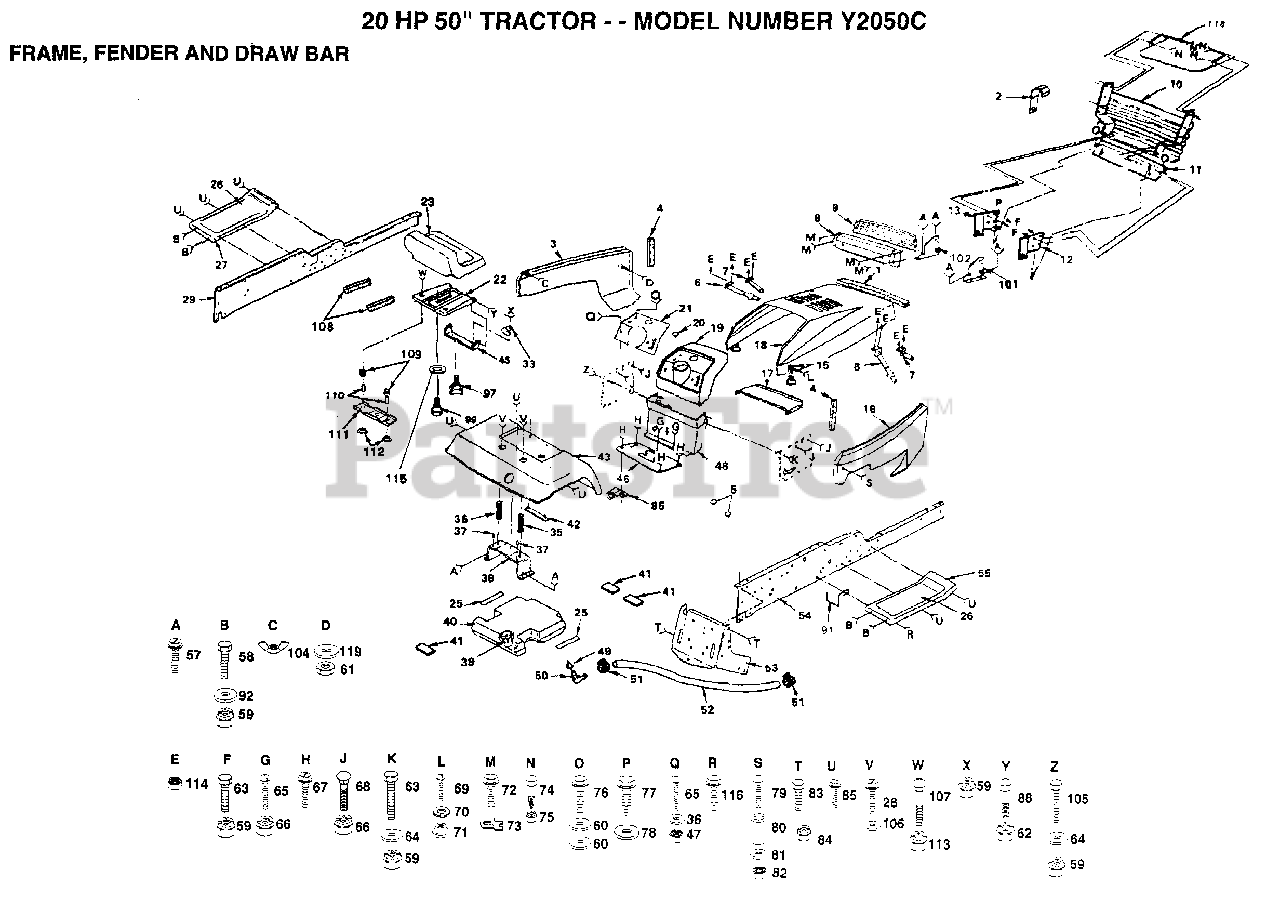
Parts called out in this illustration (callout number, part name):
1	FOAM STRIP T
4	FOAM STRIP T
5	CAP SPRING
9	LENS LT
12	SUPPORT RH YTH
13	SUPPORT LH YTH
15	HOOD LATCH T
16	"PANEL,SIDE RH "
20	PLUG-DASH T
25	PAD IDLER TI
26	FOOTREST PAD
28	SCREW LT
33	CLIP T
35	SPRING COMPRESSIO
36	WASHER
37	NUT-PUSH YT
38	BRKT.ASM.FENDER
41	PAD-SPACER LT
43	FENDER
46	SADDLE.6SP.GT
48	DASH ASSEMBLY
49	BUSHING OUTLET T
50	STEM.TANK.FUEL
51	HOSE CLAMP
57	SCREW
60	WASHER PM
63	BOLT
64	WASHER
65	SCREW
66	NUT
67	SCREW
68	BOLT
69	SCREW
70	LOCKWASHER
71	WELDNUT
73	"""J"" FASTENER LT"
76	SCREW
77	SCREW
78	WASHER
79	SCREW
80	SPACER LT
81	WASHER
83	BOLT
84	NUT GTV
85	SCREW LT
88	BOLT.SHLD.5/16-18
91	BELT RETAINER GT
92	WASHER
95	"CLIP,INSULATOR"
97	"KNOB 1/2"" YT"
99	"BOLT,SHOULDER"
101	SUPPORT RH YTH
102	SUPPORT LH YTH
106	WASHER
108	STRIP FORM
109	SPRING COMPRESSED
110	SPACER SPLIT
111	BRKT SWITCH
112	BUSHING
114	NUT
115	WASHER
116	SCREW GTV
118	"SHIELD,HEAT"
119	WASHER
